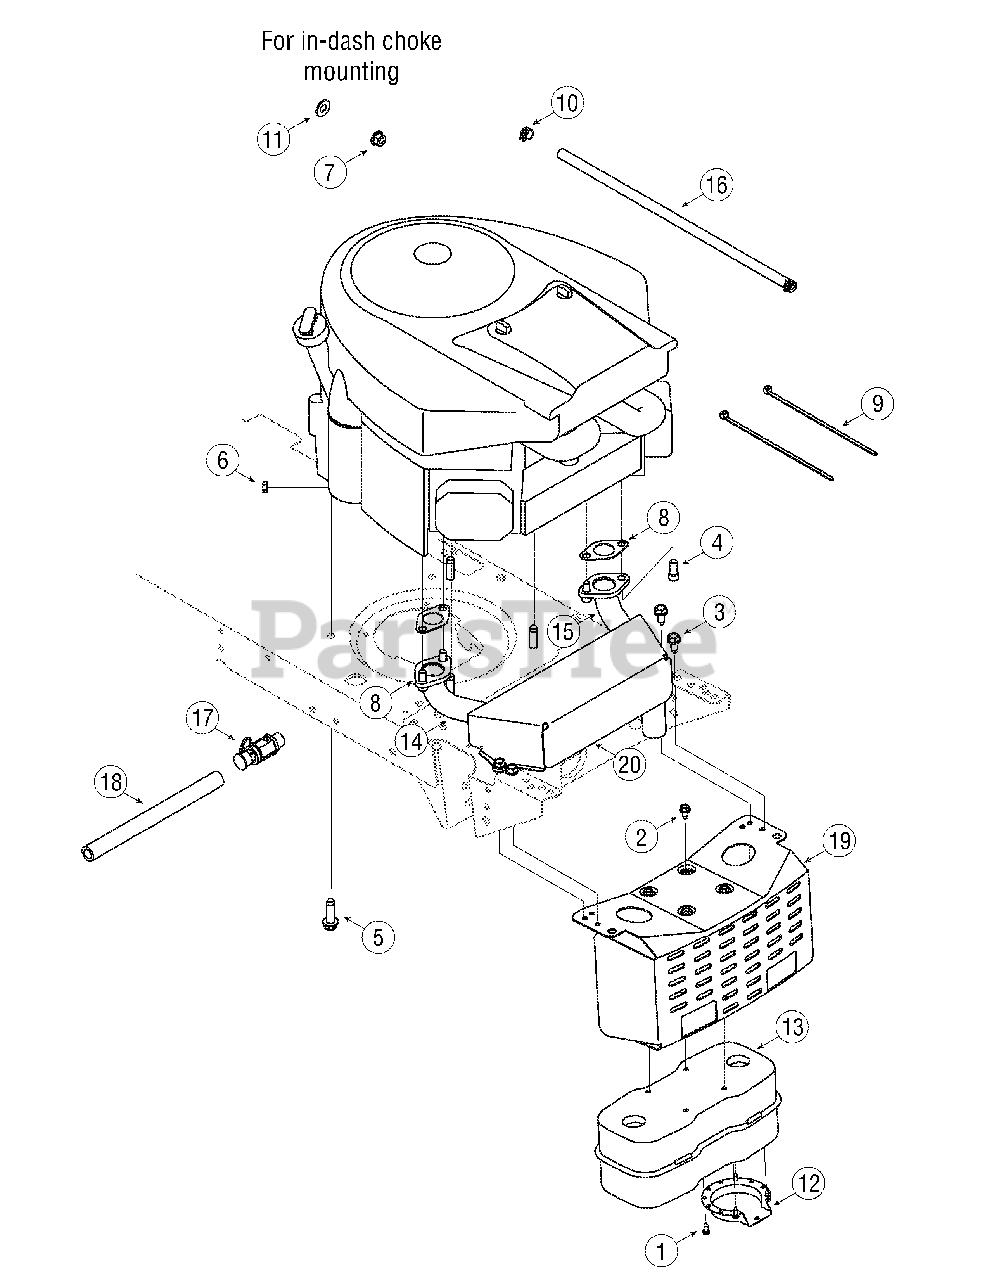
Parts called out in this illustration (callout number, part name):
1	AB Screw #8-18 x 0.5
2	TT Screw 1/4-20 x 0.5
3	AB Screw 5/16-12 x 0.5
4	Screw, 5/16-18 x .750
5	TT Screw 3/8-16 x 1.25
6	Sems Nut, 1/4-20
7	Flange Lock Nut, 3/8-16
8	Exhaust Gasket
11	Flat Washer, .406 x .875 x .059
12	Muffler Deflector
13	Dual Inlet Muffler
14	RH Exhaust Pipe
15	LH Exhaust Pipe
16	Fuel Line Hose
17	Oil Drain Valve
18	OIl Drain Extension Hose
